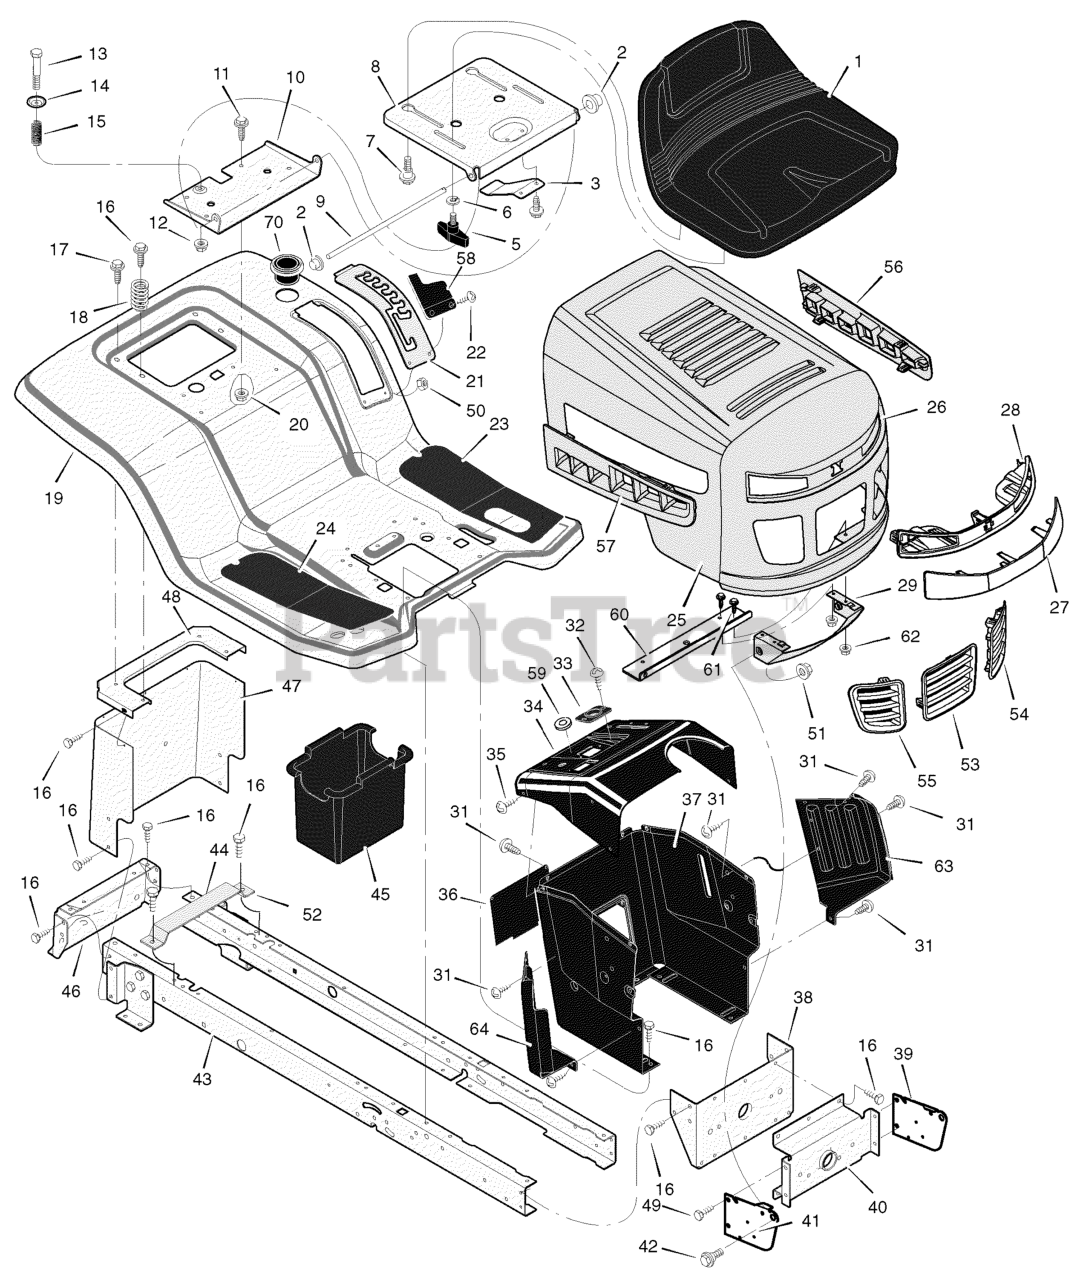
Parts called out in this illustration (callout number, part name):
2	Cap, Push 0n
3	Spring
4	Screw
5	Bolt, Wing
6	Washer
7	Bolt, Shoulder
8	Support, Seat
9	Rod, Pivot
10	Bracket, Pivot
11	Bolt
12	Nut
13	Bolt, Shoulder
15	Spring
16	Screw
17	Screw
18	Spring
19	Deck, Seat
20	Nut
21	Plate, Index
22	Screw
23	Mat, Left
24	Mat, Right
28	Housing, Light
29	Bracket, Lower Pivot
31	Screw
33	Bearing, Steering
35	Screw
36	Panel, Access
37	Support, Dash
38	Bracket, Rear Hanger
39	Support, Left Grille
40	Axle, Hanger
41	Support, Right Grille
42	Bolt, Shoulder
43	Frame, Right
44	Frame, Left
45	Container, Battery
46	Plate, Hitch
47	Plate, Rear
48	Top, Rear Plate
49	Screw
50	Nut
52	Support, Battery
53	Insert, Center Grille
54	Insert, Left Grille
55	Insert, Right Grille
56	Insert, Left Hood
57	Insert, Right Hood
58	Cover, Detent
59	Grommet, Parking Brake
60	Bracket, Support
61	Screw, Hex
63	Panel, Left Side
64	Panel, Right Side
70	Holder, Cup
